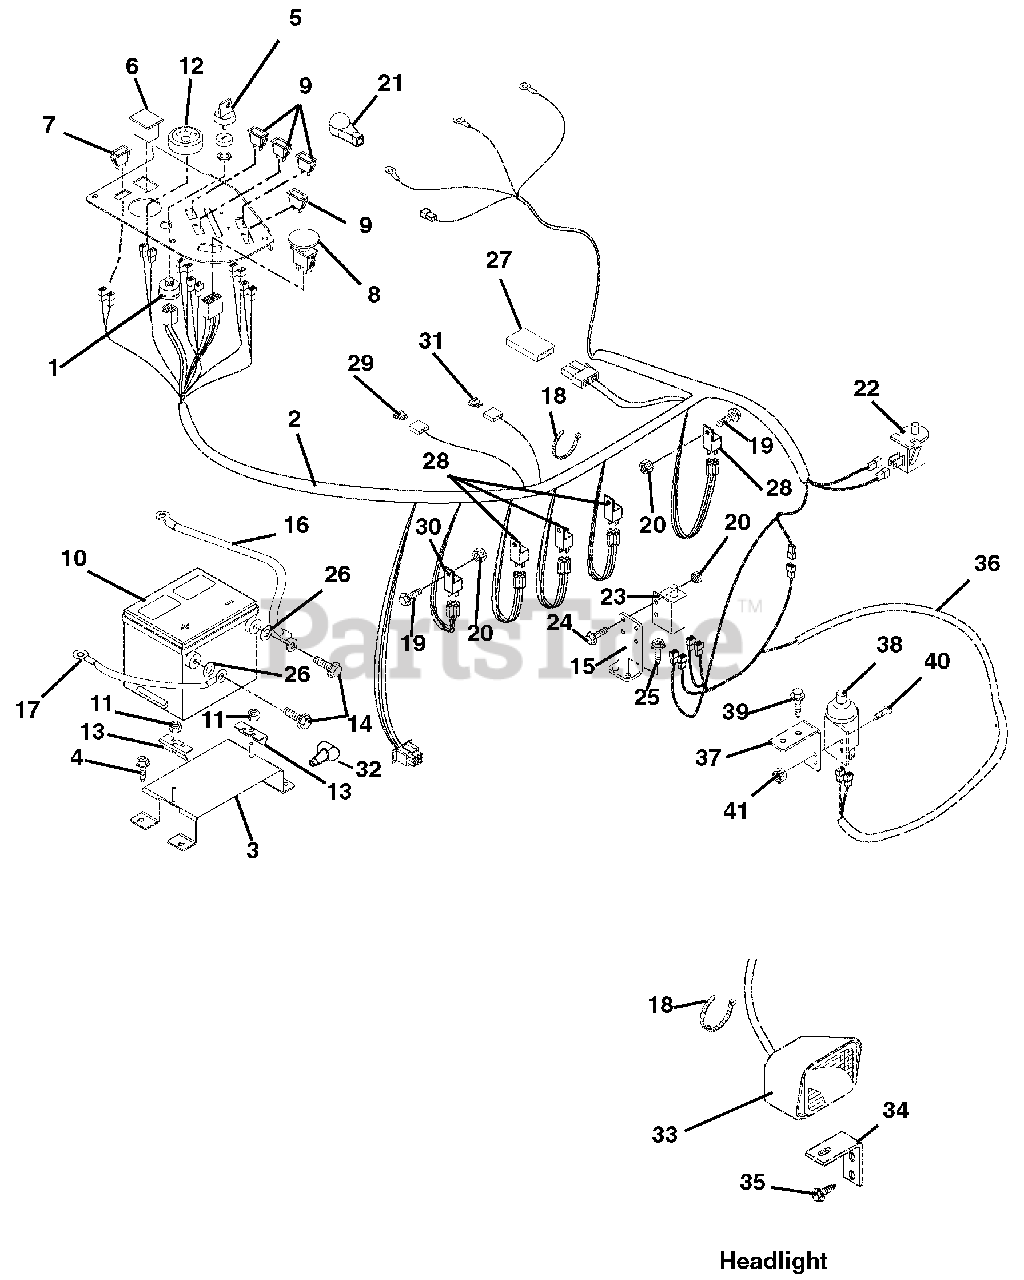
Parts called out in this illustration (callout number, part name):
1	Switch, Ignition
2	Harness, Wiring
3	Weldment, Battery Support
4	Screw, Tapping .38-16 x .75 Hex Washer Head
5	Key, with Cap
6	Hour Meter
7	Switch, Light
8	Switch, Clutch With Retainer Ring
9	Light, Indicator
10	Battery with Tube
11	Nut, Locking Top Flange .31-18
12	Gauge, Temperature
13	Bracket, Battery Hold-Down
14	Bolt, Hex .25-20 x .75 Grade 5
15	Mount, Safety Switch
16	Positive Cable w/Boots
17	Cable, Negative Battery
18	Cable Tie
19	Screw, Machine 10-24 x .75 Hex Washer Head
20	Nut, Locking Nylon 10-24 With Insert
21	Boot, Terminal, Red
22	Switch, Snap Mounting (N.O.) (Included with Seat)
23	Switch, Single Pole
24	Screw, Machine 10-24 x .75 Hex Washer Head
25	Screw, Tapping .25-20 x .50 Hex Washer Head
26	Washer, Flat Steel .406 x 1.00 x ..083
27	Diode, Connector Shell
28	Relay (Included with Harness)
29	Fuse, ATO 30 Amp (Included with Harness)
30	Pre-Heat Timer (Included with Engine)
31	Fuse, ATO 60 Amp (Included with Harness)
32	Battery Terminal Boot, Red
33	Headlight
34	Bracket, Headlight Mounting
35	Screw, Tapping, .38-16 x .50 Hex Washer Head
36	Harness, Wire Adapter, CE
37	Switch, Mount
38	Switch, Single Pole (N.O.) with Cover
39	Screw,Tapping .31-18 x .50 Hex Washer Head
40	Screw, Machine 10-24 x .75 Hex Washer Head
41	Nut, Locking, Nylon 10-24 with Insert
